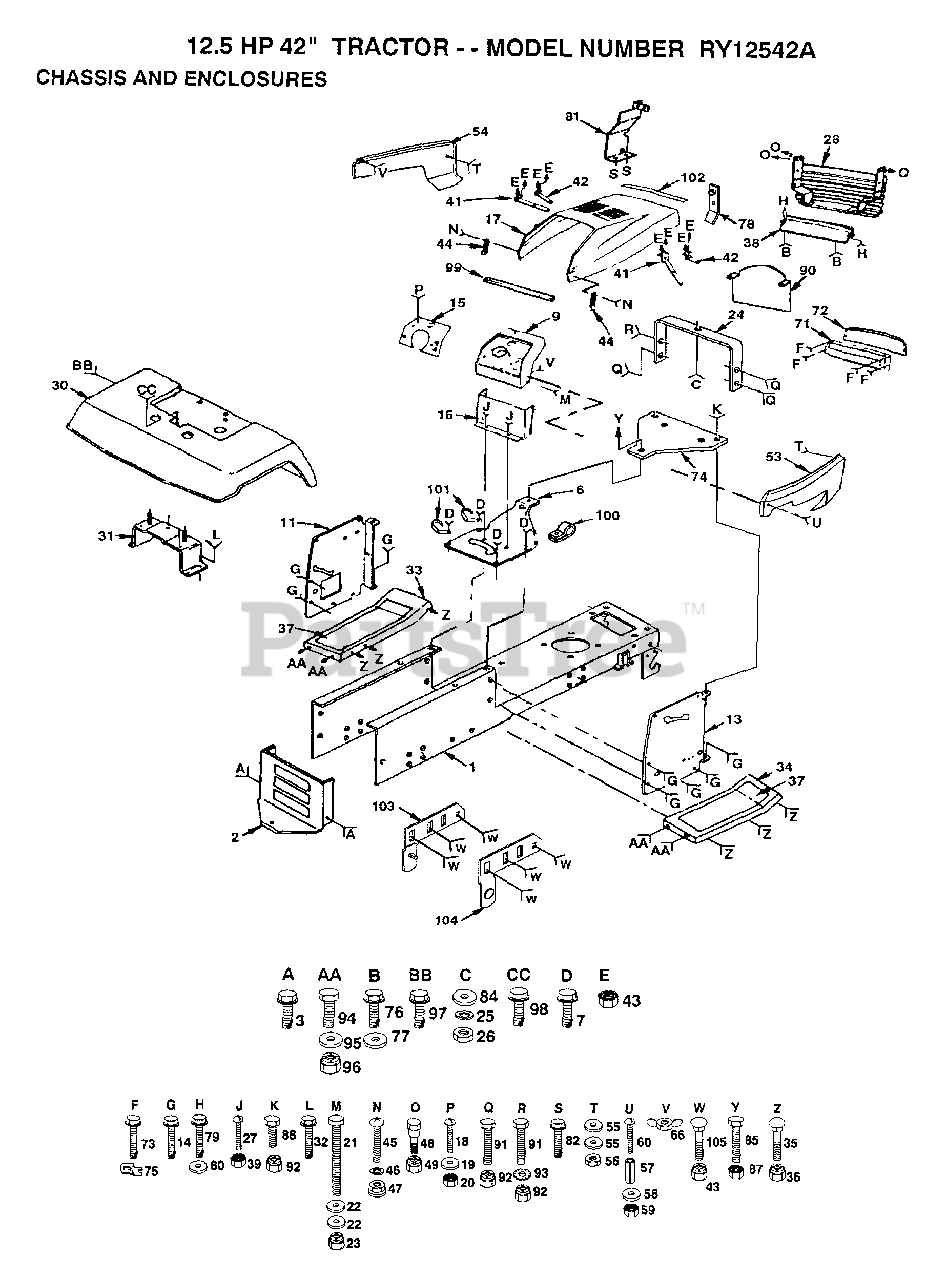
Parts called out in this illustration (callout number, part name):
3	SCREW
7	SCREW LT
11	DASH PANEL LH
13	PANEL PNT DASH RH
14	SCREW
15	DASH PLATE
18	SCREW
19	WASHER
22	WASHER
24	SUPPORT ASS'Y
25	LOCKWASHER
27	SCREW
32	SCREW
35	BOLT
37	"PAD,FOOTREST"
38	"STRAP,GRILL "
43	NUT
44	HOOD LATCH T
45	SCREW
46	LOCKWASHER
47	WELDNUT
53	"PANEL,SIDE RH"
54	"PANEL,SIDE LH"
55	WASHER PM
57	SPACER LT
58	WASHER
60	SCREW
72	LENS LT
75	"""J"" FASTENER LT"
76	SCREW
77	WASHER
79	SCREW HEX CRT
80	WASHER
82	SCREW
84	WASHER PM
85	BOLT
90	BAFFLE HOOD VERT
93	LOCKWASHER
95	WASHER
97	SCREW LT
98	SCREW
99	FOAM-STRIP LT
100	CLIP T
101	CLIP T
103	PIVOT BRKT LH
104	PIVOT BRKT RH
105	BOLT
